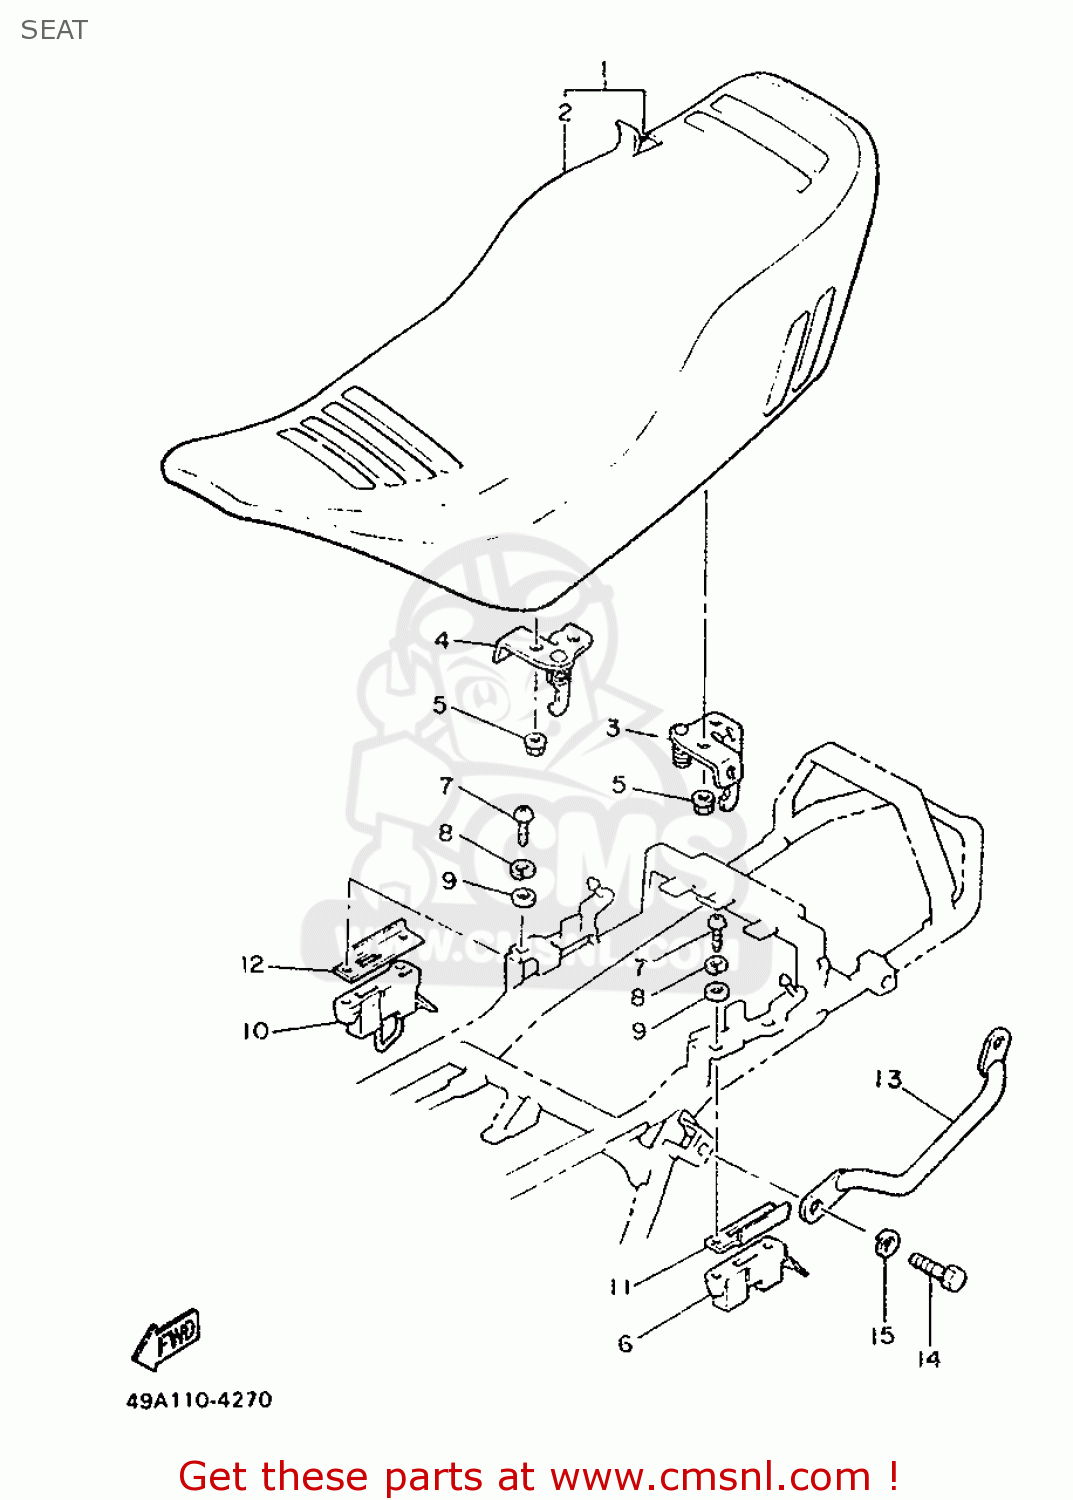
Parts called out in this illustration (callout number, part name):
01	DOUBLE SEAT ASSY
02	COVER, DOUBLE SEAT
03	BRACKET, SEAT
04	BRACKET, SEAT
05	NUT, FLANGE (7G0)
06	SEAT LEVER ASSY
07	SCREW, PAN HEAD
08	WASHER,SPRING
09	WASHER, PLAIN (646)
10	SEAT LOCK ASSY
11	PLATE, GUIDE 1
12	PLATE, GUIDE 2
13	HANDLE, STANDING
14	BOLT (3W3)
15	WASHER,SPRING
